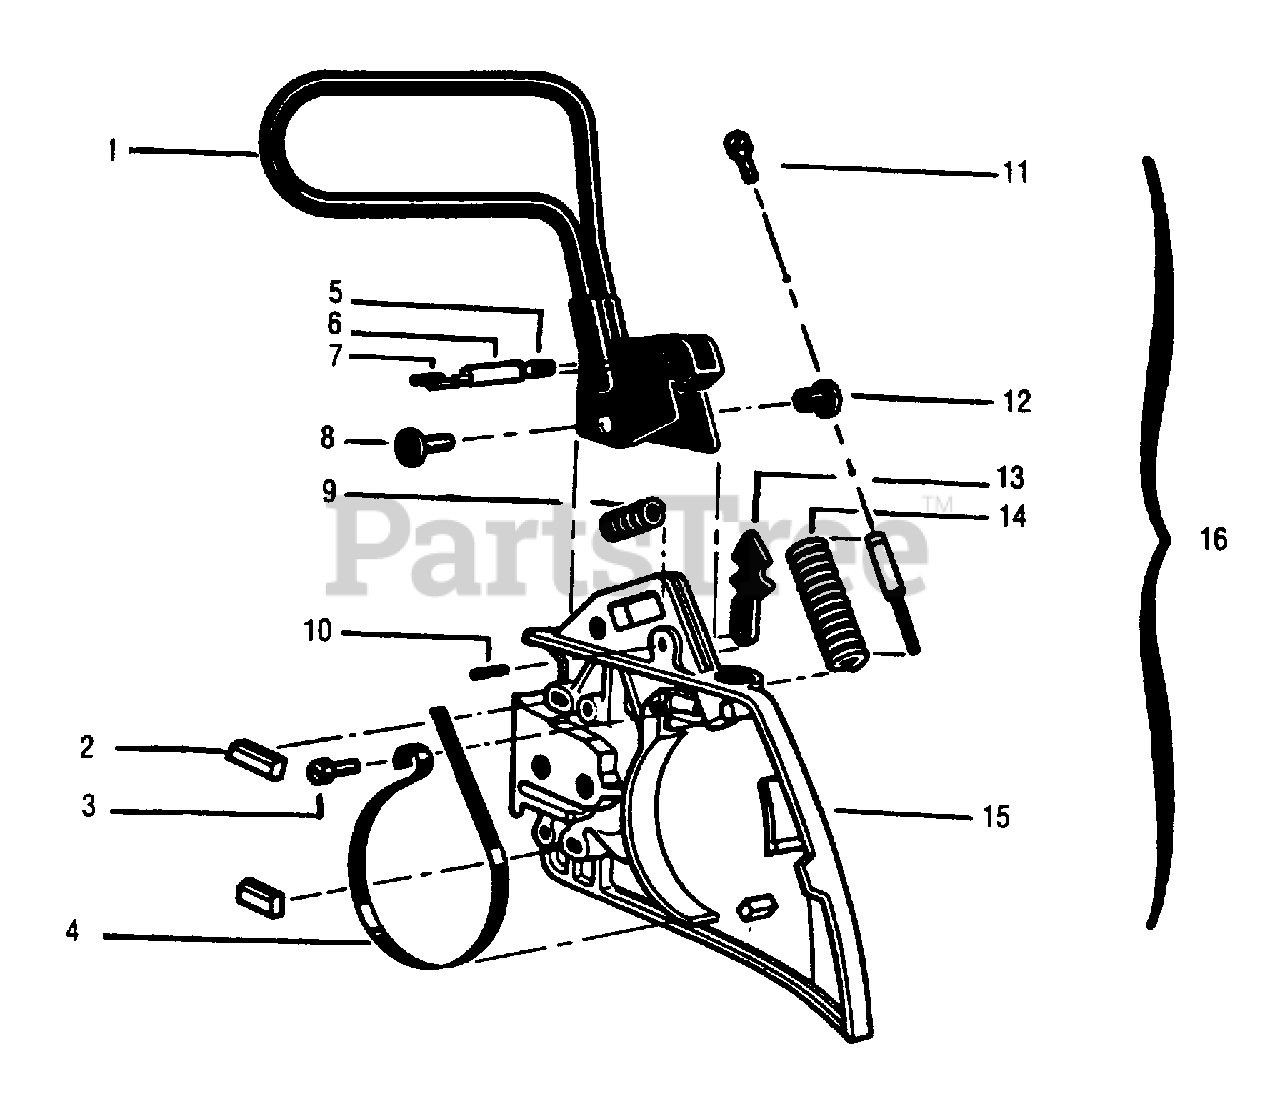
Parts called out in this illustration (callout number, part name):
1	Assy-Handguard
2	Pad-Chain
3	Screw Sems #10-24
4	Assy-Brake Band
5	Roller Latch
6	Sleeve-Roller Latch
7	Spiral Pin (1/8")
8	Screw Hex Socket
9	Spring-Pawl Compression
10	Spiral Pin (3/16")
11	Screw Adjustment
12	Pivot Nut
14	Spring-Band Compression
15	Bar Clamp
16	Complete Chain Brake
17	Decal Chain Brake 3000 CB
